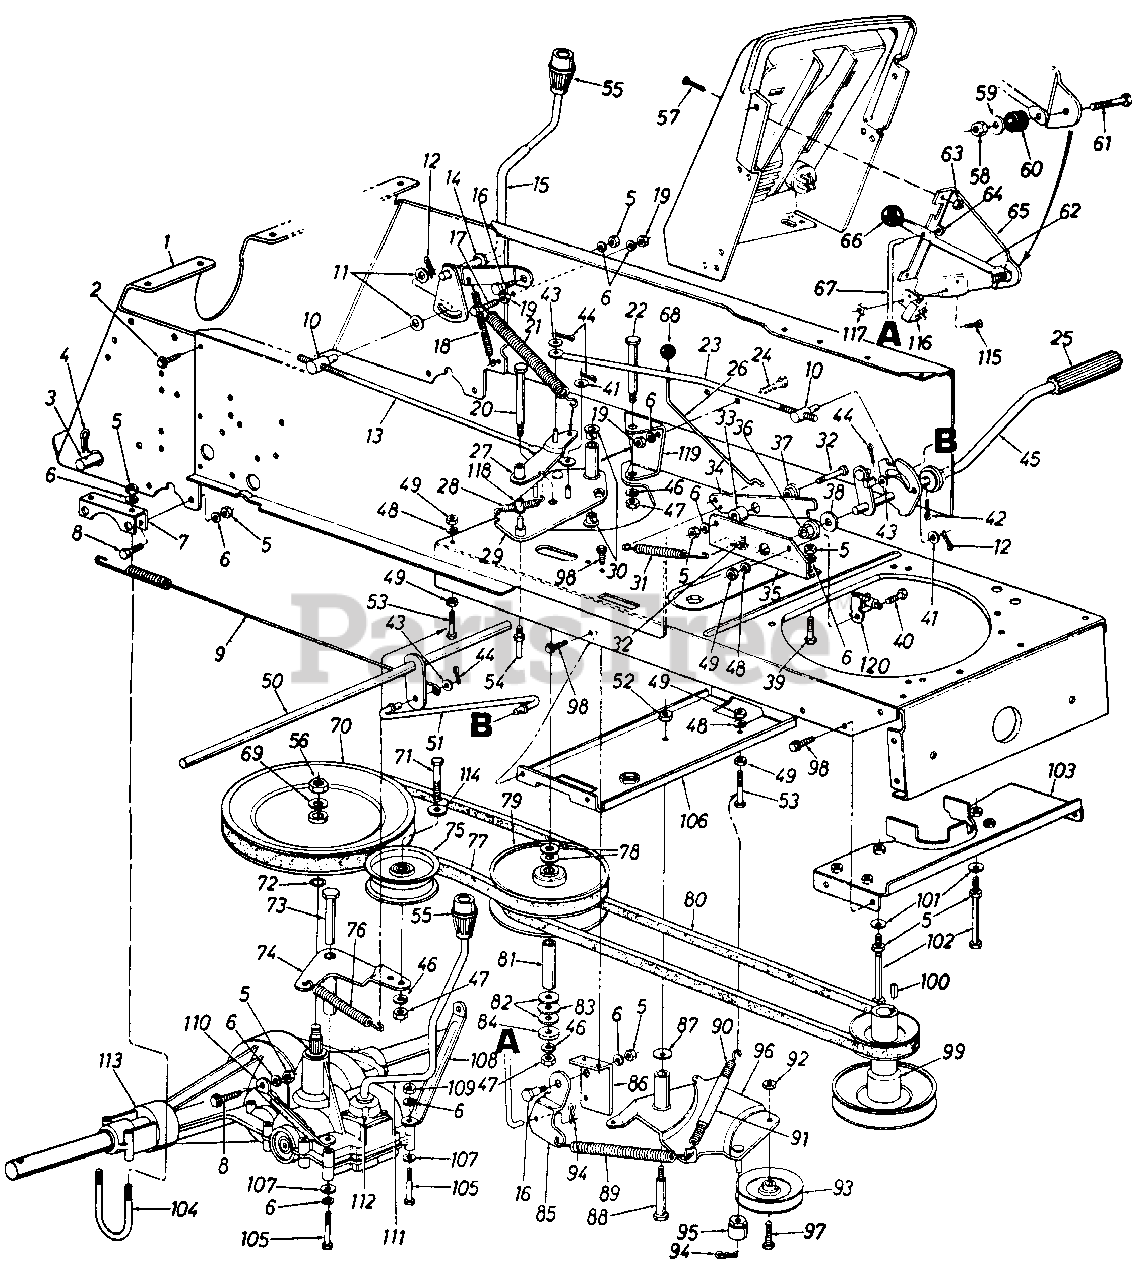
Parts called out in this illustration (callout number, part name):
4	Hitch Pin Clip
5	Hex Nut 5/16-18 Thd.
6	L-Wash. 5/16" I.D.
7	Transaxle Bracket
8	Hex Bolt 5/16-18 x .75" Lg. (Gr. 5)
9	Brake Extension Spring
10	Adjustment Ferrule 3/8-24 Thd.
11	Fl-Wash. .385" I.D. x .87"
12	Internal Cotter Pin
13	Speed Control Link
14	Fl-Wash. .531" I.D. x .94"
15	Speed Selector Lever Ass'y.
16	Shld. Bolt .437" Dia. x .162"
17	Hex Bolt 5/16-24 x 1.25" Lg.
18	Extension Spring 3.9" Lg.
19	Hex Nut 5/16-24 Thd. (Gr. 5)
20	Hex Bolt 3/8-24 x 4.5" Lg.
21	Extension Spring 11" Lg.
22	Shld. Bolt .625" Dia. x 3.5" Lg.
23	Speed Control Link
24	Hex Bolt 5/16-24 x .75" Lg.
25	Foot Pad
26	Parking Brake Link
27	Variable Speed Torque Brkt. Ass'y.
28	Extension Spring 2.59" Lg.
29	Pulley Brkt. Sub Ass'y.
30	Flanged Brg. .625" I.D.
31	Extension Spring 2.51" Lg.
32	Hex Bolt 5/16-18 x 1.25" Lg.
33	Spacer .34" I.D. x .88"
36	Hex Flange Brg. .634" I.D.
37	Shld. Spacer .5" Dia.
38	Fl-Wash. .64" I.D. x 1.24"
39	Hex Bolt 5/16-18 x .75" Lg.
40	Hex Bolt 1/4-20 x .62" Lg.
41	Fl-Wash. .406" I.D. x .75" O.D.
42	Cotter Pin 1/8" Dia.
43	Fl-Wash. .34" I.D. x .68" O.D.
44	Cotter Pin 3/32" Dia.
45	Foot Pedal Brkt. Ass'y.
46	L-Wash. 3/8" I.D.
47	Hex Nut 3/8-24 Thd.
48	L-Wash. 1/4" I.D.
49	Hex Nut 1/4-20 Thd.
50	Brake Link Bracket
51	Front Brake Rod Link
52	Hex Cent. L-Nut 3/8-16 Thd.
53	Hex Bolt '/4-20 x 2.0" Lg.
54	Belt Guard Pin
56	Hex Jam Nut 9/16-18 Thd.
57	Truss Mach. Scr. '/4-20 x .5" Lg.
58	Hex Ins. L-Nut '/4-20 Thd.
59	Fl-Wash. .281" I.D. x .73" O.D.
60	Rubber Washer .33" I.D.
61	Hex Bolt 1/4-20 x 1.25" Lg.
62	Blade Clutch Lever
63	Hex Sems Nut 1/4-20 Thd.
64	Push Nut 1/4" O.D. Rod
65	Deck Clutch Control Brkt.
66	Knob-Blade Clutch
67	Deck Control Rod
68	Ball Knob Brake
69	Bell-Wash. 9/16" I.D. x 1.25"
70	V-Pulley 9-1/4" O.D.
71	Hex Bolt 3/8-24 x 1.75' Lg.
73	Shld. Bolt 5/16-24 Thd.
74	Idler Brkt. Ass'y.
75	Flat Idler 3.5" O.D.
76	Extension Spring 6.12" Lg.
77	V-Belt
78	Teflon Washer 1.20" O.D.
79	Variable Speed Pulley 6" Dia.
80	V-Belt
81	Pivot Bushing
82	Fl-Wash. .56" I.D. x 1.0" O.D.
83	Thrust Brg. .56" I.D. x 1.25"
84	Retainer Cup
85	Deck Control Pivot Brkt.
86	Parking Brake Mtg. Brkt.
87	Bell-Wash. .38" I.D. x .88" O.D.
88	Shld. Bolt .498" Dia. x 2.05"
89	Extension Spring 6.12" Lg.
90	Extension Spring 6.37" Lg.
91	Convoluted Conduit 4" Lg.
92	Hex Cent. L-Nut 3/8-24 Thd.
93	V-Belt Idler
94	Internal Cotter Pin
95	Spacer
96	Idler Brkt. Deck Ass'y.
97	Hex Bolt 3/8-24 x 1.5" Lg.
98	Hex TT-Tap Scr. 1/4-20 x .5"
99	Engine Pulley
100	Sq. Key 1/4 x 1.5" Lg.
101	Bell-Wash. .345" I.D. x .88"
102	Hex Bolt 5/16-18 x 5.25" Lg.
103	Belt Keeper Brkt. Ass'y.
105	Hex Bolt 5/16-24 x 2.25" Lg.
106	Deck Idler Support Brkt.
107	Fl-Wash. .344" I.D. x .62" O.D.
108	Front Trans. Support Brkt.-L.H.
109	Hex Nut 5/16-24 Thd.
110	Front Trans. Support Brkt.-R.H.
111	Shift Lever Ass'y. Complete
112	Socket Hd. Cap Scr. #10 x 24
113	2-Speed Transmission Comp.
114	Fl-Wash. 3/8" I.D. x 1.0" O.D.
115	Truss Mach. Scr. #10-24 x .5"
116	Safety Switch
117	Hex Nut #10-24 Thd.
118	Nyliner Flanged Brg.
119	Variable Speed Support Brkt.
120	Safety Switch
